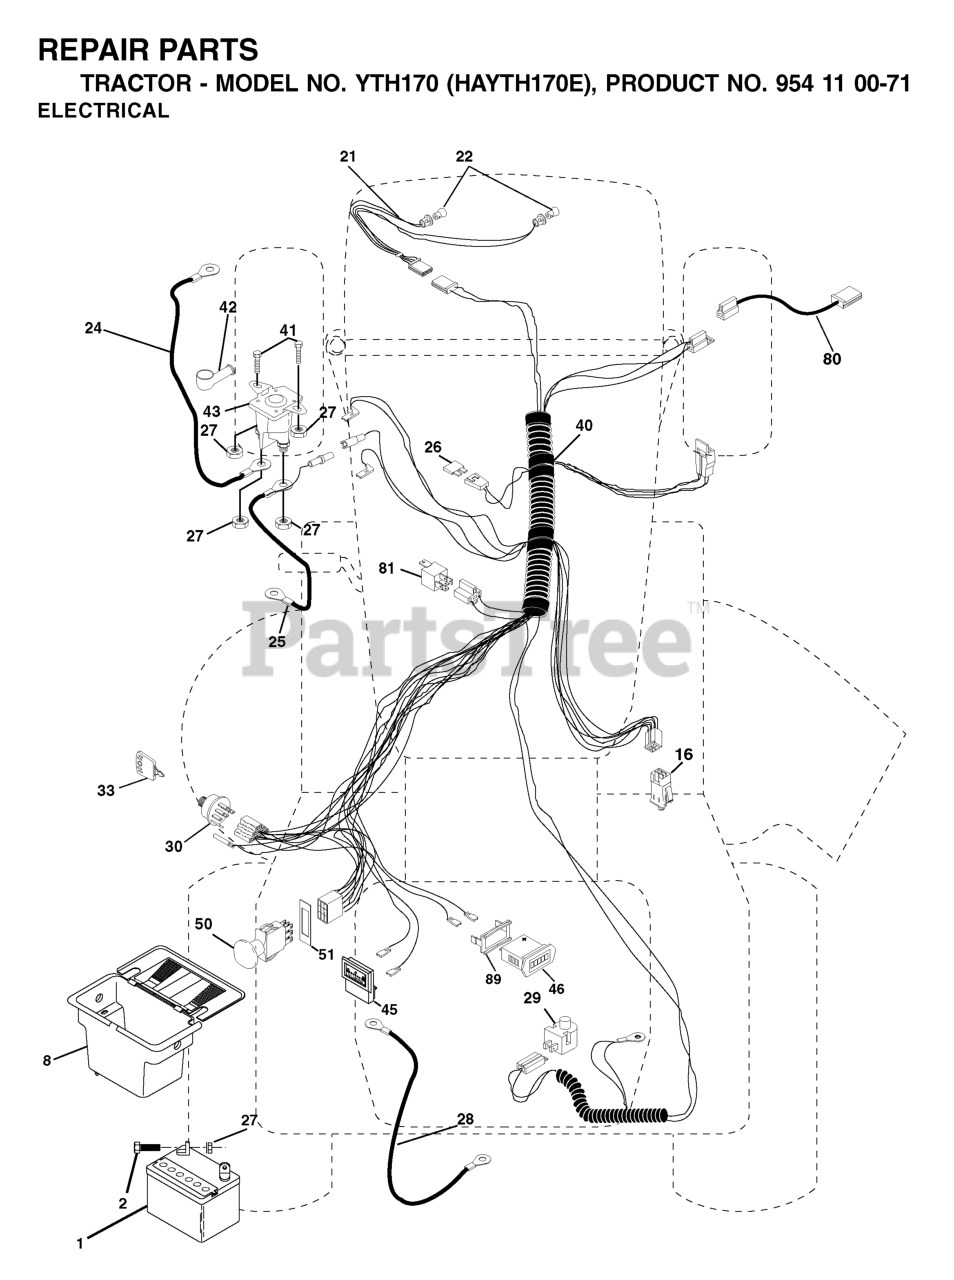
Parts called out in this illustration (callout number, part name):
1	Battery 12 Volt 25 Amp
2	BOLT.HEX.1/4.X.3/4.DICHROMATE
8	CASE BATTERY MECH HINGE
16	SWITCH INTERLOCK
24	BATTERY CABLE GT
25	CABLE BATTERY
26	FUSE 15 AMP
27	NUT
28	CABLE T
29	PLUNGER SWITCH (COLOR:OLIVE)
30	SWITCH IGN
33	KEY MLD GEN DELTA
40	HARNESS IGN.
41	BOLT
42	TERMINAL COVER
43	SOLINOID
45	AMMETER
46	HOUR METER
50	PTO SWITCH
51	FRAME RETAINING RING
80	HARNESS, CLUTCH
81	RELAY.ASSY.T
89	BRACKET SNAP-IN HOURMETER
